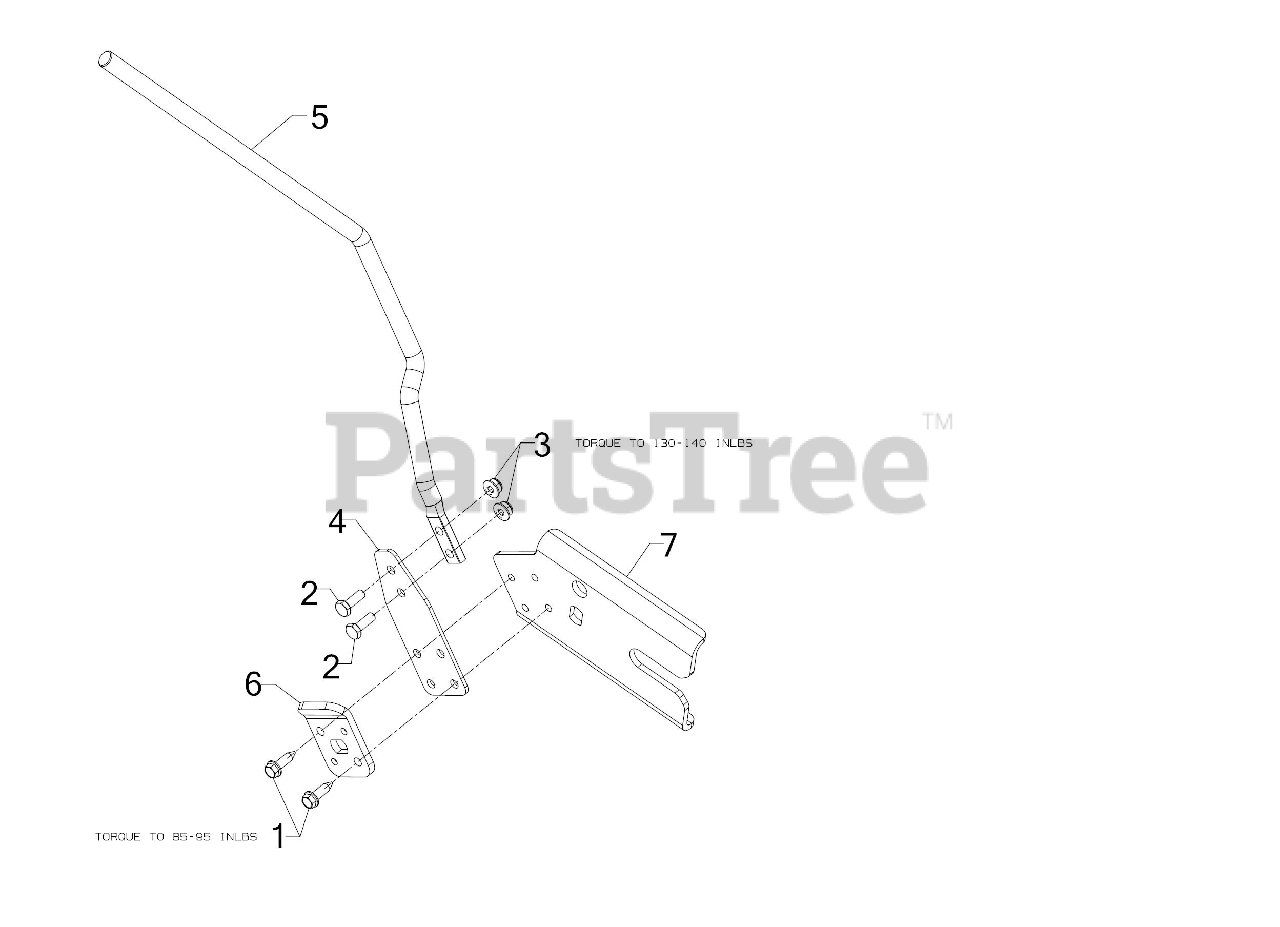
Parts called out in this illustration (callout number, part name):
1	SCREW-TT 1/4-20 x .875
2	SCREW 1/4-20X.75 GR5
3	FLANGE LOCK NUT
4	LOCK PLATE LEVER
5	HEIGHT LOCK LEVER
6	HEIGHT LEVER BRACKET
7	HEIGHT PIVOT BRACKET
